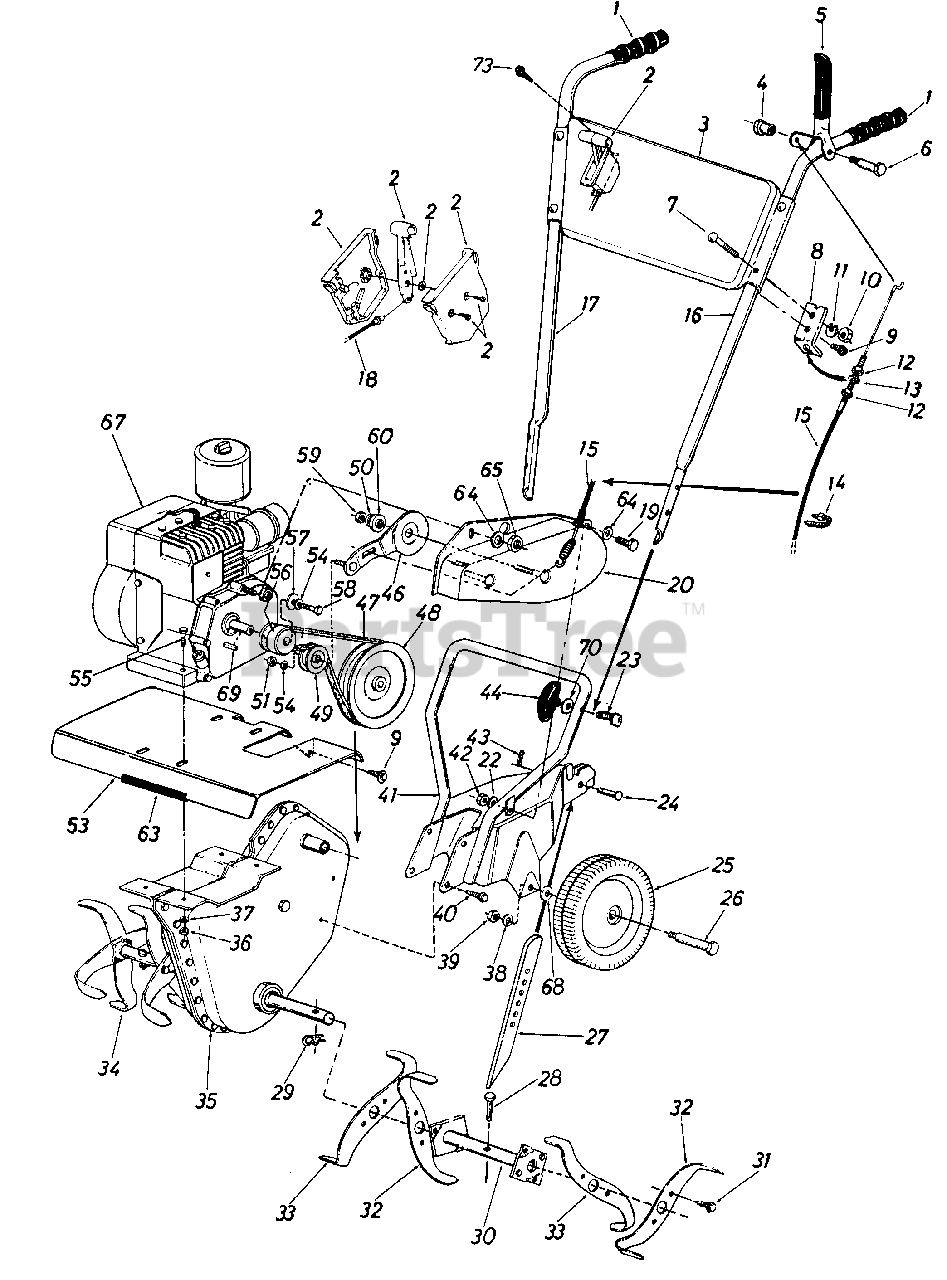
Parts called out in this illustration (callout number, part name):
2	CONTROL-THROTTLE
3	PANEL-HANDLE
4	NUT-SHLD
5	GRIP ASSY-CLUTCH-RH
6	SCREW-SHLD
7	BOLT-CARRIAGE 5/16-18 x 1.50
8	BRACKET-CLUTCH
9	SCREW-HEX WASH SF TAPP
10	NUT-HEX 5/16-18
11	WASHER-LOCK-5/16
12	NUT-HEX JAM 5/16-24
13	WASHER-LOCK-5/16
14	TIE-CABLE
15	CABLE-CLUTCH
19	SCREW-HEX 1/4-20 x .75
20	COVER-BELT
22	LOCK WASHER 1/4 DIA
23	BOLT-CARRIAGE 5/16-18 x 1.75
24	PIN-CLEVIS
25	WHEEL ASSY W/TIRE
26	SCREW-SHLD .498 DIA x 1.450 LG THD
27	BAR-DEPTH
28	PIN-CLEVIS
29	PIN-INTERN COT
34	TINE ASSY-COMP
35	CASE ASSY-CHAIN COMP
36	NUT-HEX 5/16-18
37	WASHER-LOCK-5/16
38	WASHER-HDL 3/8
39	NUT-HEX CENTER L-3/8-16
40	SCREW-HEX WASH SF TAPP
43	PIN-INTERN COT-5/16 DIA
44	KNOB-HANDLE ASSY
46	ARM-IDLER
47	BELT-V 3/8 x 29
49	CABLE-CLUTCH CONT
50	WASHER-LOCK-5/16
51	NUT-HEX INS L-3/8-24
55	SCREW-HEX 5/16-18 x 1.50
57	WASHER-FL-.385 x 1.00 x .135
58	BOLT-3/8 NF x 1"GR5
59	NUT-HEX 5/16-18
60	WASHER-BUSHING
63	STRIP-TRIM-12IN
64	WASHER-FL-.281 ID x .50 OD x .063
65	NUT-HEX CENTER L-1/4-20
68	WASHER-BELL .3/8ID x 1.12OD x .030
69	KEY-SQ 3/16 x .75
70	WASHER-BELL .337 x .867 x .057
73	SCREW-TRUSS TAP
